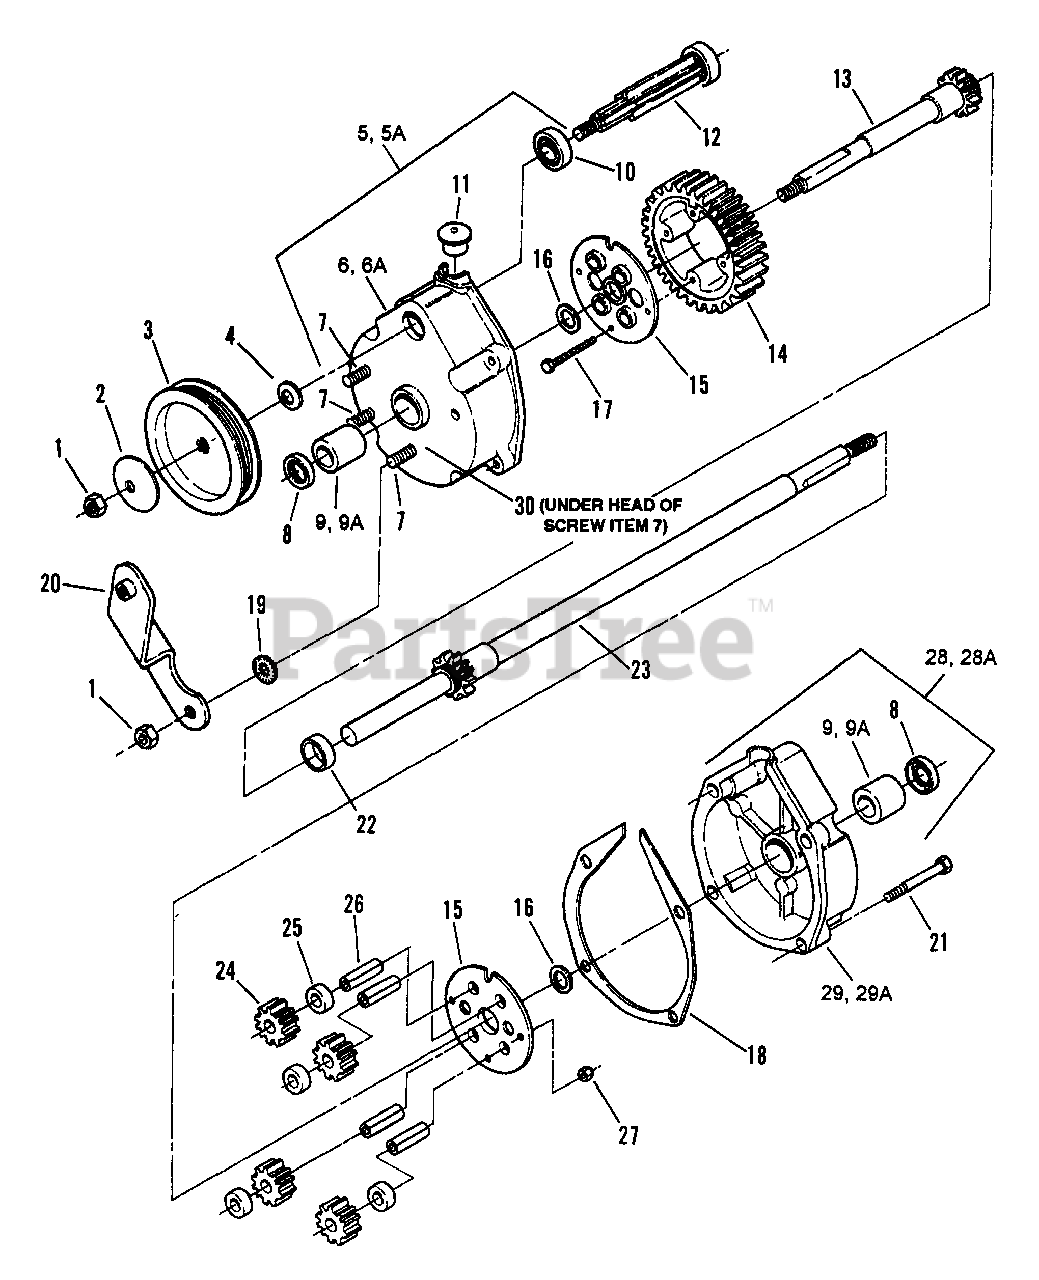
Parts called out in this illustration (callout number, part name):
1	NUT, 5/16-24 Hex Lock, Grade C
2	WASHER, Spring
3	PULLEY, Poly-Vee Belt
4	WASHER, Spring
5	ASSEMBLY, Housing Right
5A	ASSEMBLY, Housing Right
6	HOUSING, Right Side
6A	HOUSING, Right Side
7	SCREW, 5/16-24 x 1-1/8" Rib Neck, Grade 5
8	SEAL, 5/8 I.D.
9	BEARING, Differential
9A	BEARING, Differential
10	BEARING, Ball
11	PLUG, Housing
12	GEAR, Input
13	AXLE, Short
14	GEAR, Differential (46 Tooth)
15	PLATE
16	WASHER, Thrust
17	SCREW, #10-32 x 1-1/2" Hex Head Cap, Grade 5
18	GASKET, Housing
19	WASHER, 5/16 Internal/External Tooth Lock
20	BRACKET, Differential
21	SCREW, 1/4-20 x 1-1/4" Self-Tapping
22	SPACER, Axle Gear
23	AXLE, Long
24	GEAR, Pinion (12 Tooth)
25	SPACER, Pinion Gear
26	SHAFT, Pinion
27	NUT, #10-32 Hex Nyloc
28	ASSEMBLY, Housing Left
28A	ASSEMBLY, Housing Left
29	HOUSING, Left Side
29A	HOUSING, Left Side
30	GASKET, 5/8 O.D.
